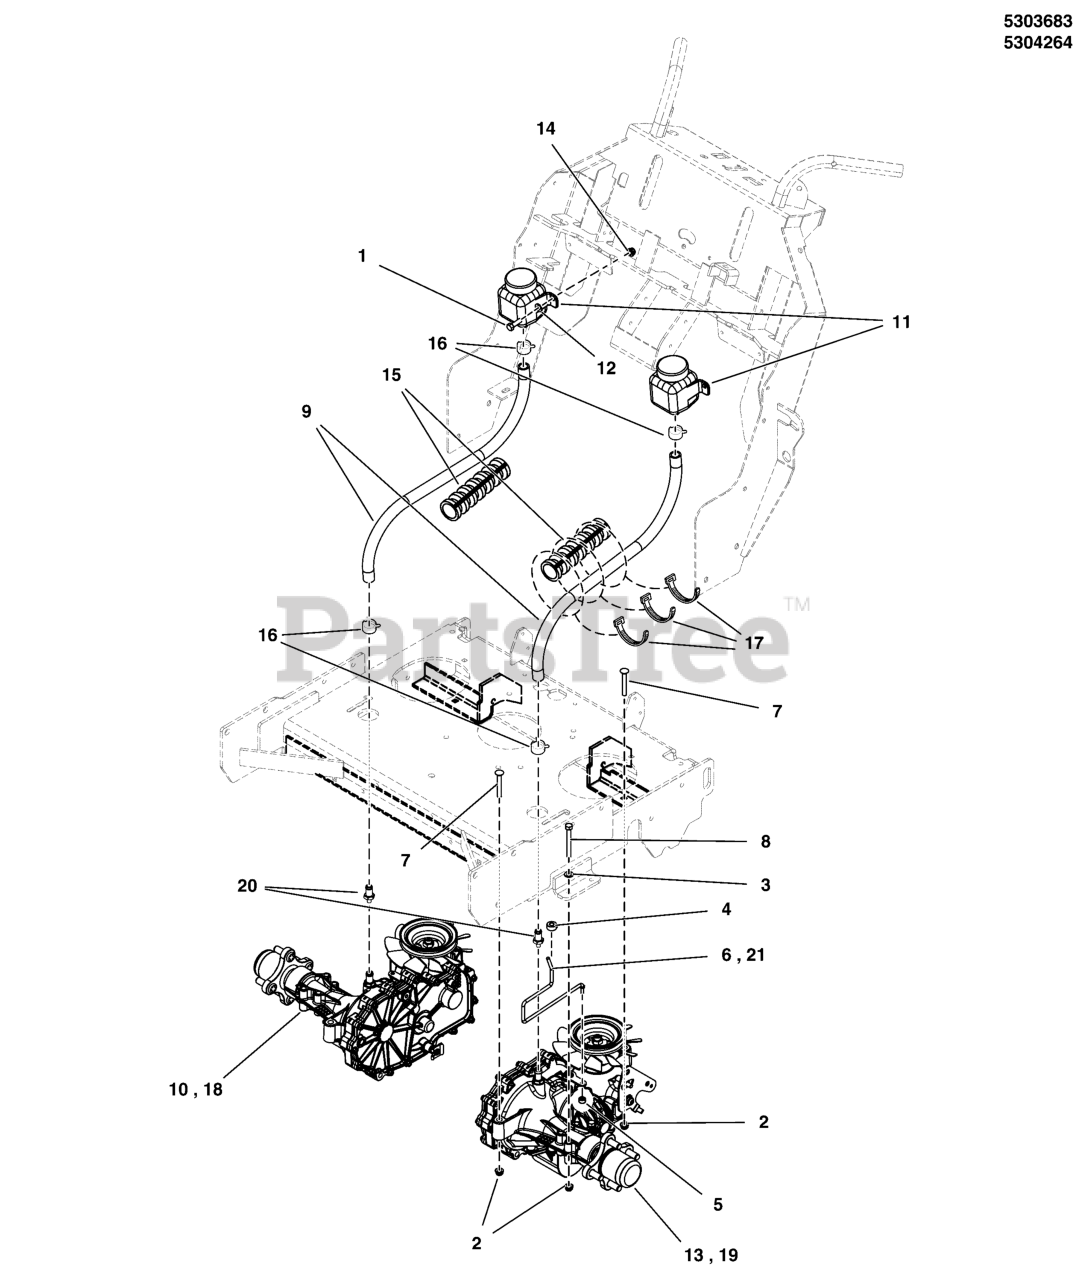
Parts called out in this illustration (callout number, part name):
1	BOLT, 1/4-20 X 3/4 GD5 YZ
2	NUT, 5/16-18 HEX NYLOCK FLANGE
3	WASHER, 5/16" SAE
4	COLLAR, 5/16 SET
5	COLLAR, 1/4 SET
6	ROD, HYDRO RELEASE, SW30
7	BOLT, 5/16-18 X 2-1/4, CARRIAGE, GD5, CZ
8	BOLT, 5/16-18 X 2-3/4, GD 5, YZ
9	HOSE, 1/2" PUSH-ON, 24.00"
10	TRANSAXLE, ZT3100, RH(ZJ-KMFE-3B5C-1RLX)
11	HYDRO RES. #71328, 350 ml
12	WASHER, 1/4 SAE
13	TRANSAXLE, ZT3100, LH(ZJ-GMFE-3B5B-1RLX)
14	NUT, 1/4-20 HEX NYLOCK FLANGE
15	WIRE LOOM, 3/4 ID X 20 IN
16	CLAMP, HOSE, .75 FREE DIA.
17	TIE, SELF LOCKING, 15"
18	TRANSAXLE, ZT3100, RH, ZL-KMFE-3L5C-1PXE
18	TRANSAXLE, ZT-3100, RH,ZL-KMFE-SL5C-1PXX
19	TRANSAXLE, ZT3100, LH, ZL-GMFE-3L5B-1PXE
19	TRANSAXLE, ZT-3100, LH,ZL-GMFE-SL5B-1PXX
20	FITTING, #6 O-RING 1/2 HOSE BARB, STRAIGHT
21	ROD, HYDRO RELEASE, WALKS
